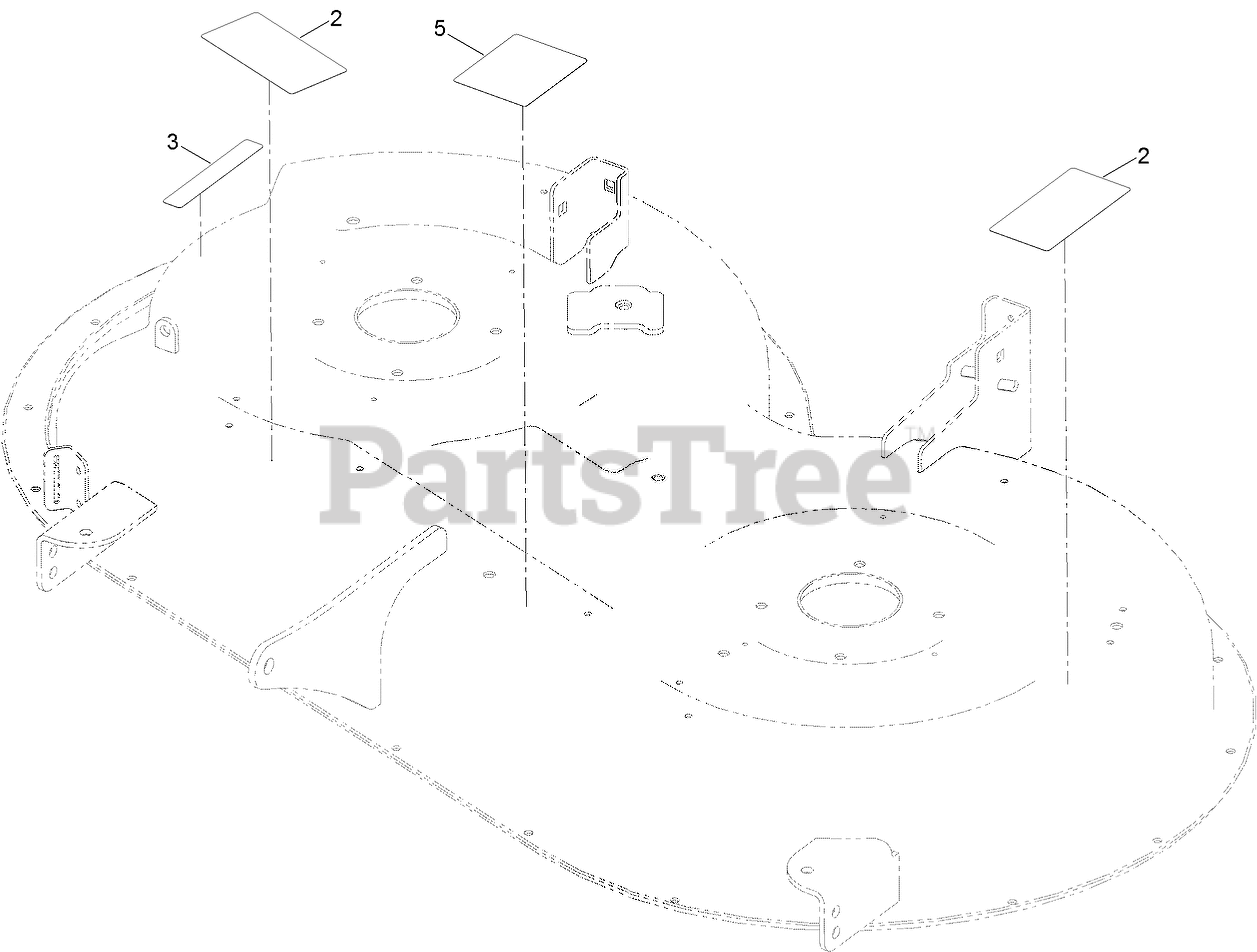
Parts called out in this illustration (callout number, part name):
2	DECAL-DANGER, DECK
3	DECAL-DANGER
5	DECAL-ROUTING, BELT
